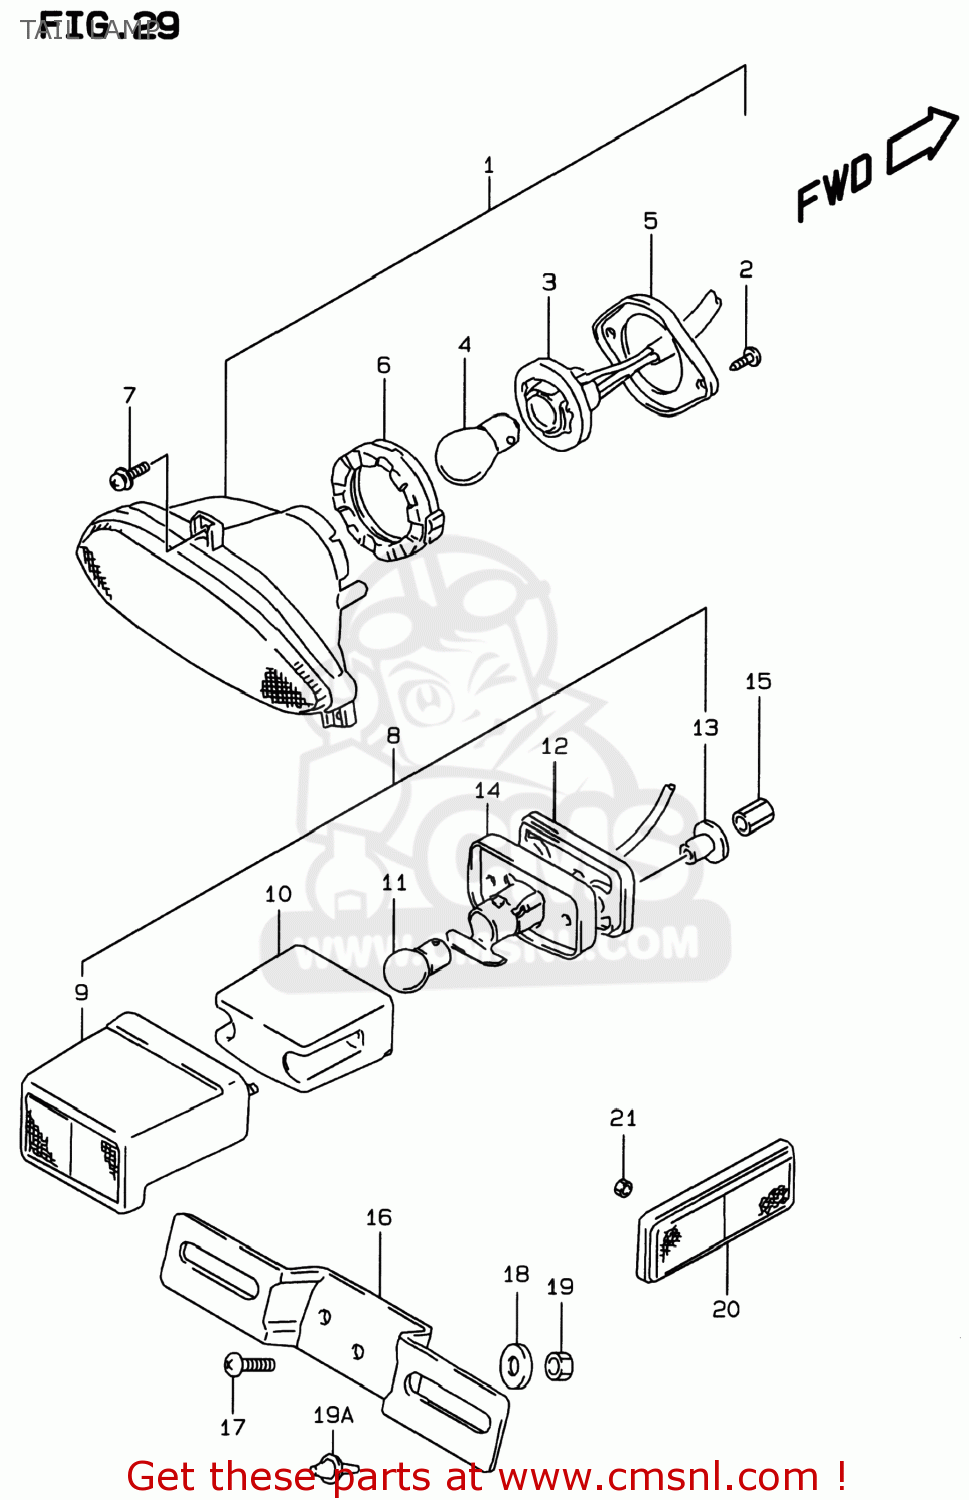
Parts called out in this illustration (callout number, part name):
1	LAMP ASSY,RR COMBINATION
2	SCREW
3	SOCKET & CORD
4	BULB(12V21/5W)
5	PLATE NO.2
6	CUSHION
7	TPG SCREW
8	LAMP ASSY,LICENSE PLATE
9	COVER,LICENSE
10	LENS
11	BULB
12	CUSHION
13	SPACER
14	GASKET,LICENSE LAMP (NAS)
15	NUT
16	BRACKET,LICENSE PLATE
17	SCREW 6X12
18	WASHER(6.5X20X1.6)
19	NUT 6MM
19A	CUSHION
20	REFLECTOR ASSY,RR
21	NUT
